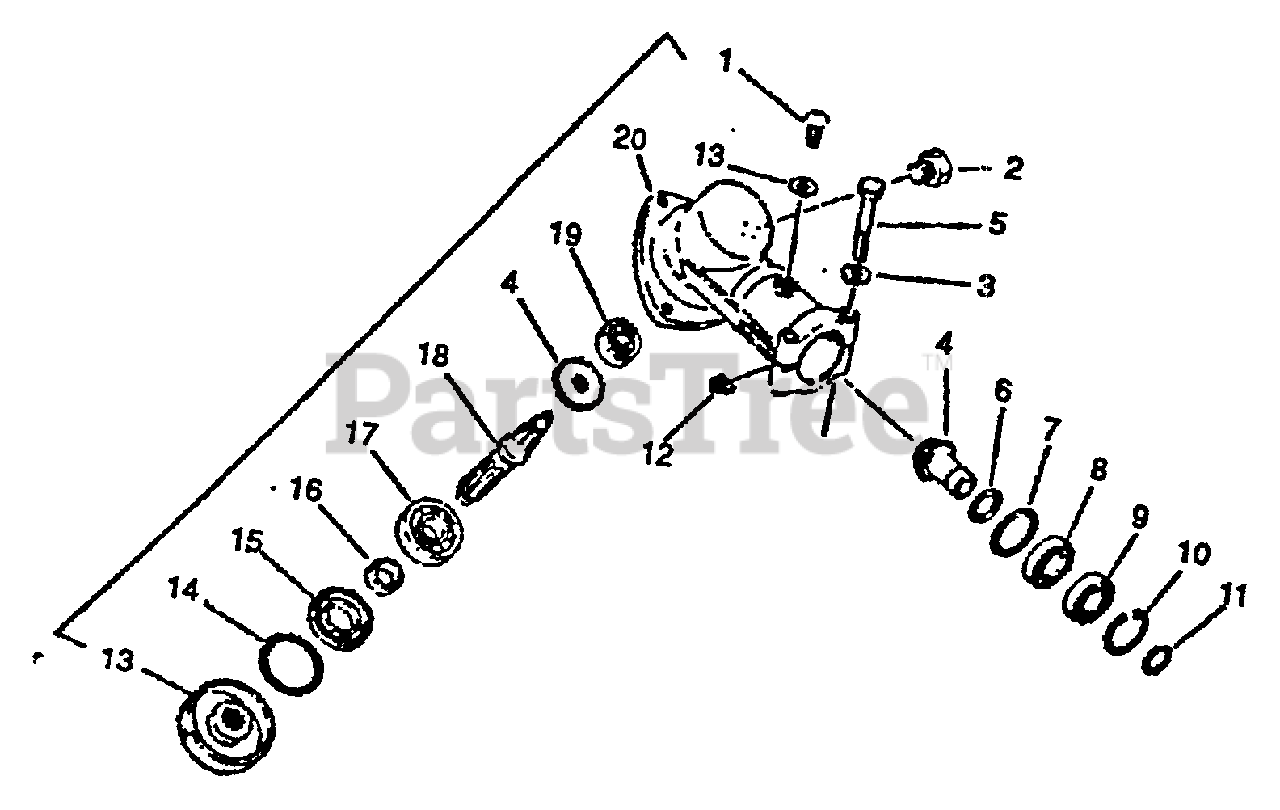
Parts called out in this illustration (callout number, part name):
1	SCREW 5×10
2	BOLT 8×8 SP
3	WASHER, FLAT 5.5×10×0.8
4	GEAR SET
5	BOLT 5×35 SP
8	BEARING, BALL 6900
9	BEARING, BALL 6900Z
10	RING, SNAP Ø22
11	RING, SNAP Ø10
13	PLATE, ADAPTER - UPPER
14	RING, SNAP 26
15	SEAL, OIL
17	BEARING, BALL 6000
18	SHAFT, GEAR
19	BEARING, BALL 626
20	CASE, GEAR
